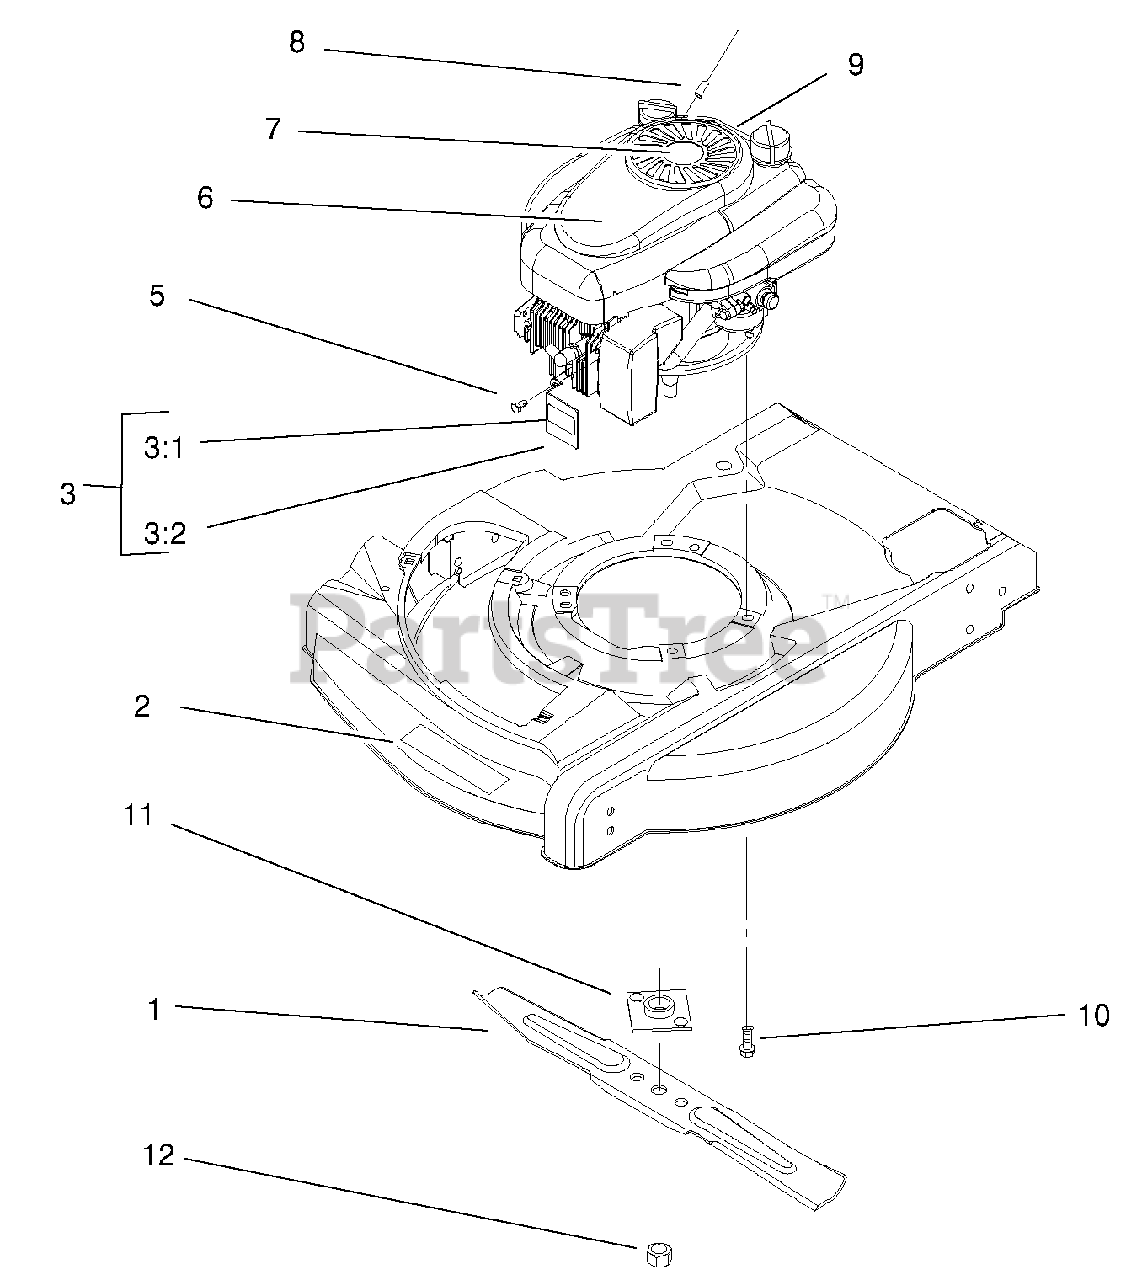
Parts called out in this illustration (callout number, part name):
2	DECAL-DECK
3	ASM-Guard,Muffler (only on: 10270c)
3	ASM-Muffler Guard (only on: 10270)
3:1	Decal-Surface, Hot-International (only on: 10270c)
3:1	Decal-Surface, Hot (only on: 10270)
3:2	GUARD - MUFFLER
6	APPLIQUE
7	DECAL-RECOIL,5HP
8	STOP-ROPE
9	Engine (Tecumseh Lev115-350181e)
10	SCREW-TAPTITE W/PATCH
11	BLADE RETAINER ASM
12	NUT-BLADE
